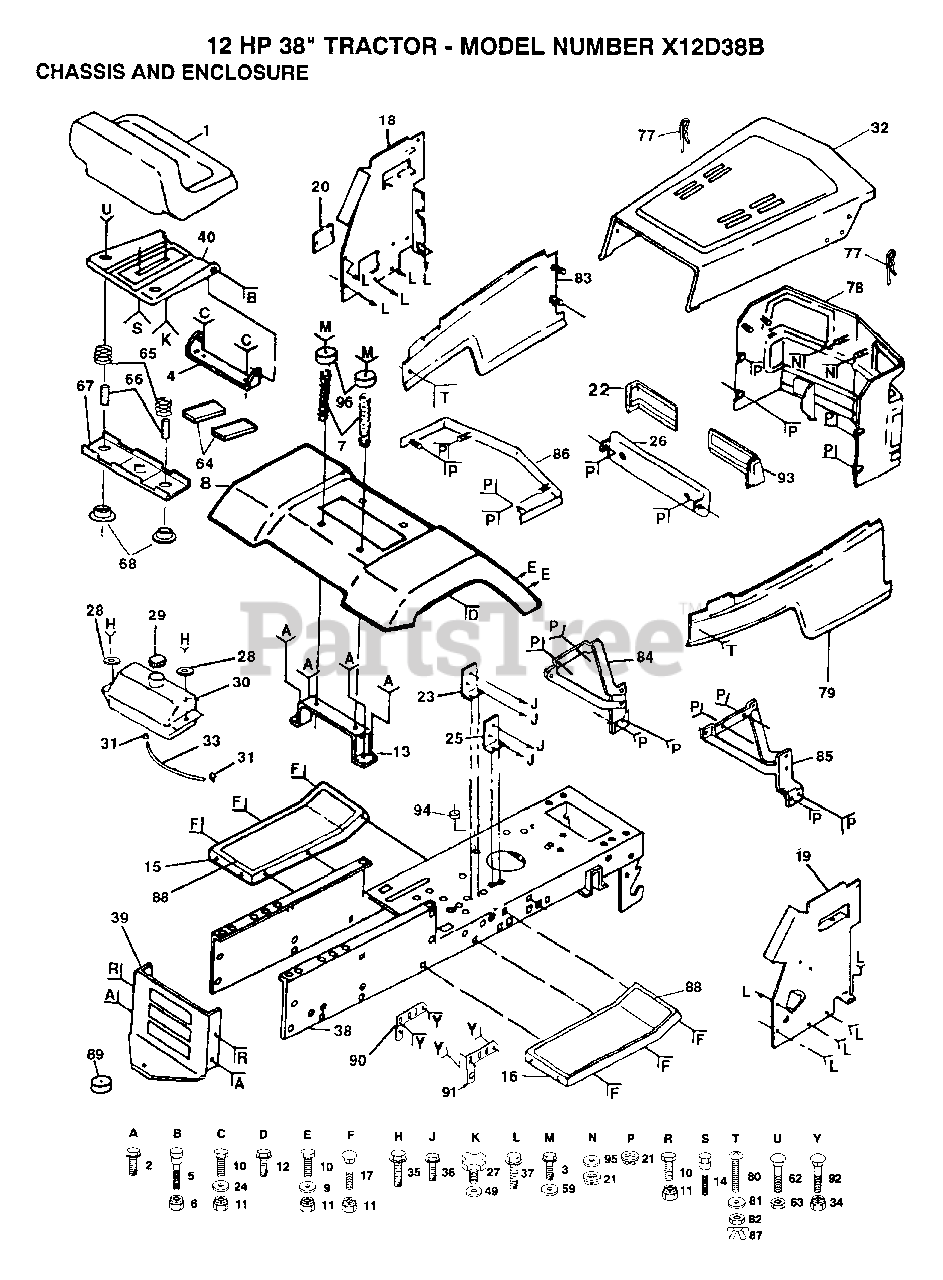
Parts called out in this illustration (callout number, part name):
2	SCREW
3	SCREW GTV
7	SPRING COMPRESSIO
9	WASHER
12	SCREW LT
14	"BOLT,SHOULDER"
17	BOLT
18	PANEL DASH LH
20	COVER ACCESS
21	PAL NUT LT
23	SWITCH BRACKET
24	WASHER
25	BRACKET LT
27	"KNOB 1/2"" YT"
28	WASHER
30	TANK.FUEL.LT.
31	HOSE CLAMP
34	NUT
35	SCREW HEX CRT
36	SCREW
37	SCREW LT
39	DRAWBAR LT/YT
49	WASHER
59	WASHER
64	STRIP FORM
65	SPRING
66	SPLIT SPACER
67	BRKT SWITCH
68	BUSHING
77	SPRING.RETAINER
79	"SIDE PANEL,RH"
80	"SCREW,SPECIAL"
82	RETAINER
83	"SIDE PANEL,LH"
84	"HINGE,HOOD,LH T"
85	"HINGE,HOOD,RH T"
87	"GROMMET,PLASTIC"
88	FOOTREST PAD
90	BRKT ASM PIVOT LH
91	BRKT ASM PIVOT RH
92	BOLT
94	SNAP BUSHING T
95	WASHER PM
96	CAP SPRING
